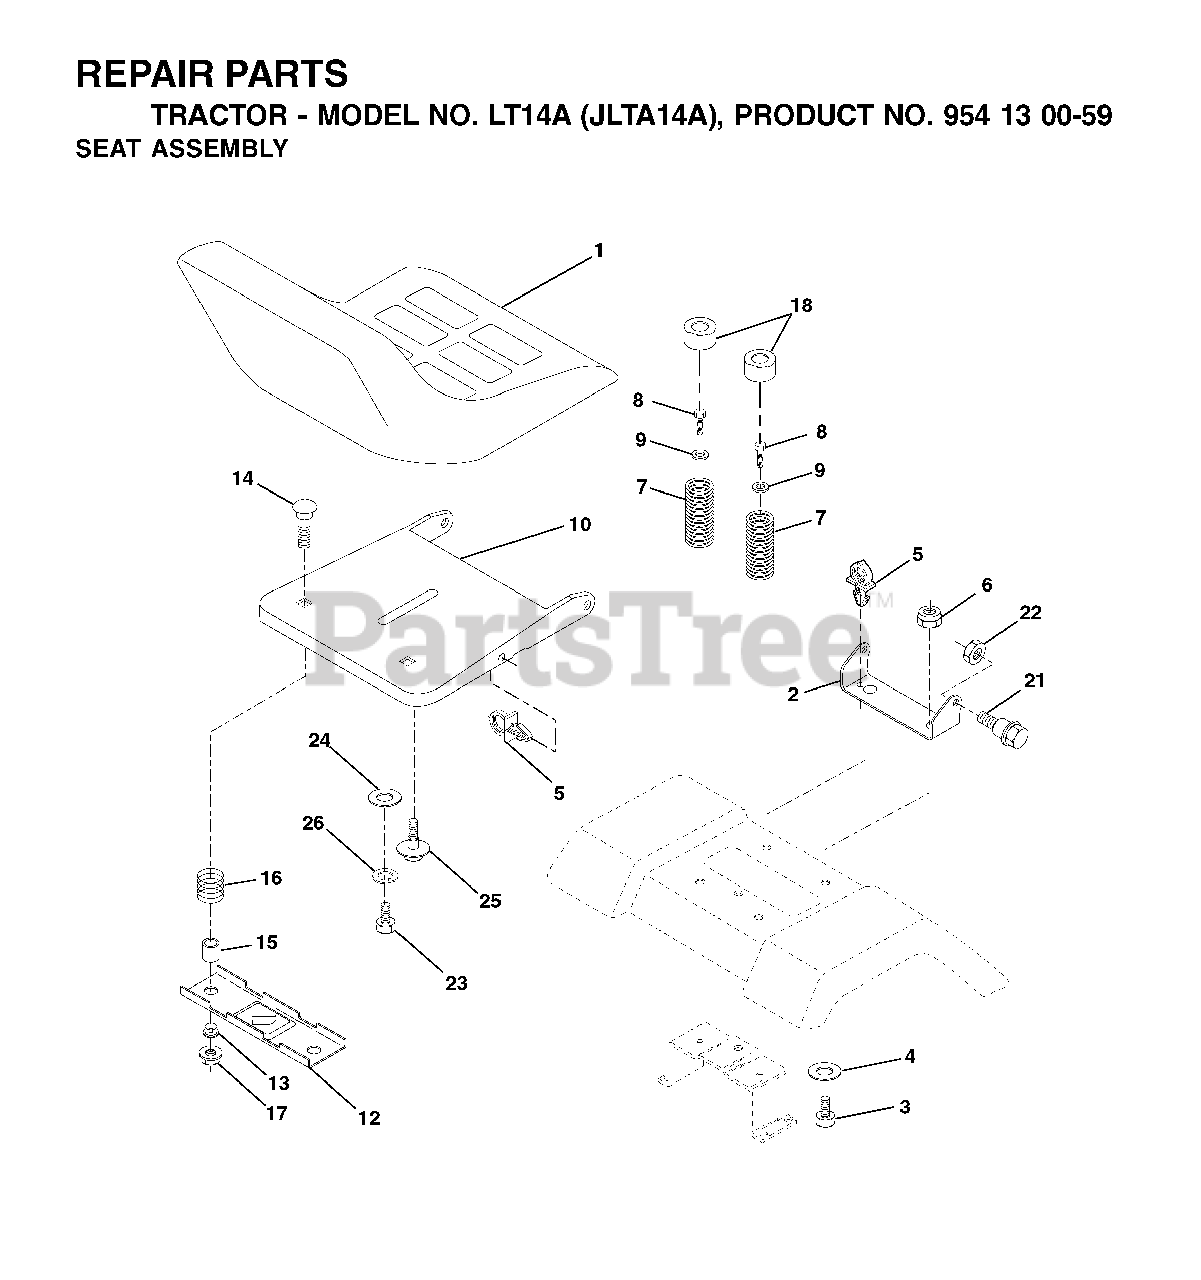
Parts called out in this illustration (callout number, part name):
2	SEAT PIVOT BRKT
4	WASHER PM
5	PUSH CLIP
6	NUT
7	SPRING COMPRESSION
8	SCREW 3/8-16X1
9	WASHER
10	PAN SEAT
12	BRKT SWITCH
14	BOLT.ROUND.HEAD.SQUARE.NECK
15	SPACER SPLIT 28X.96
17	NUT T
18	CAP SPRING
21	BOLT.SHOULDER.5/16-18
22	NUT.71038.31-18.HEX.NYLOCK
23	BOLT.HEX.BLACK
25	BOLT,SHOULD
26	LOCKWASHER
